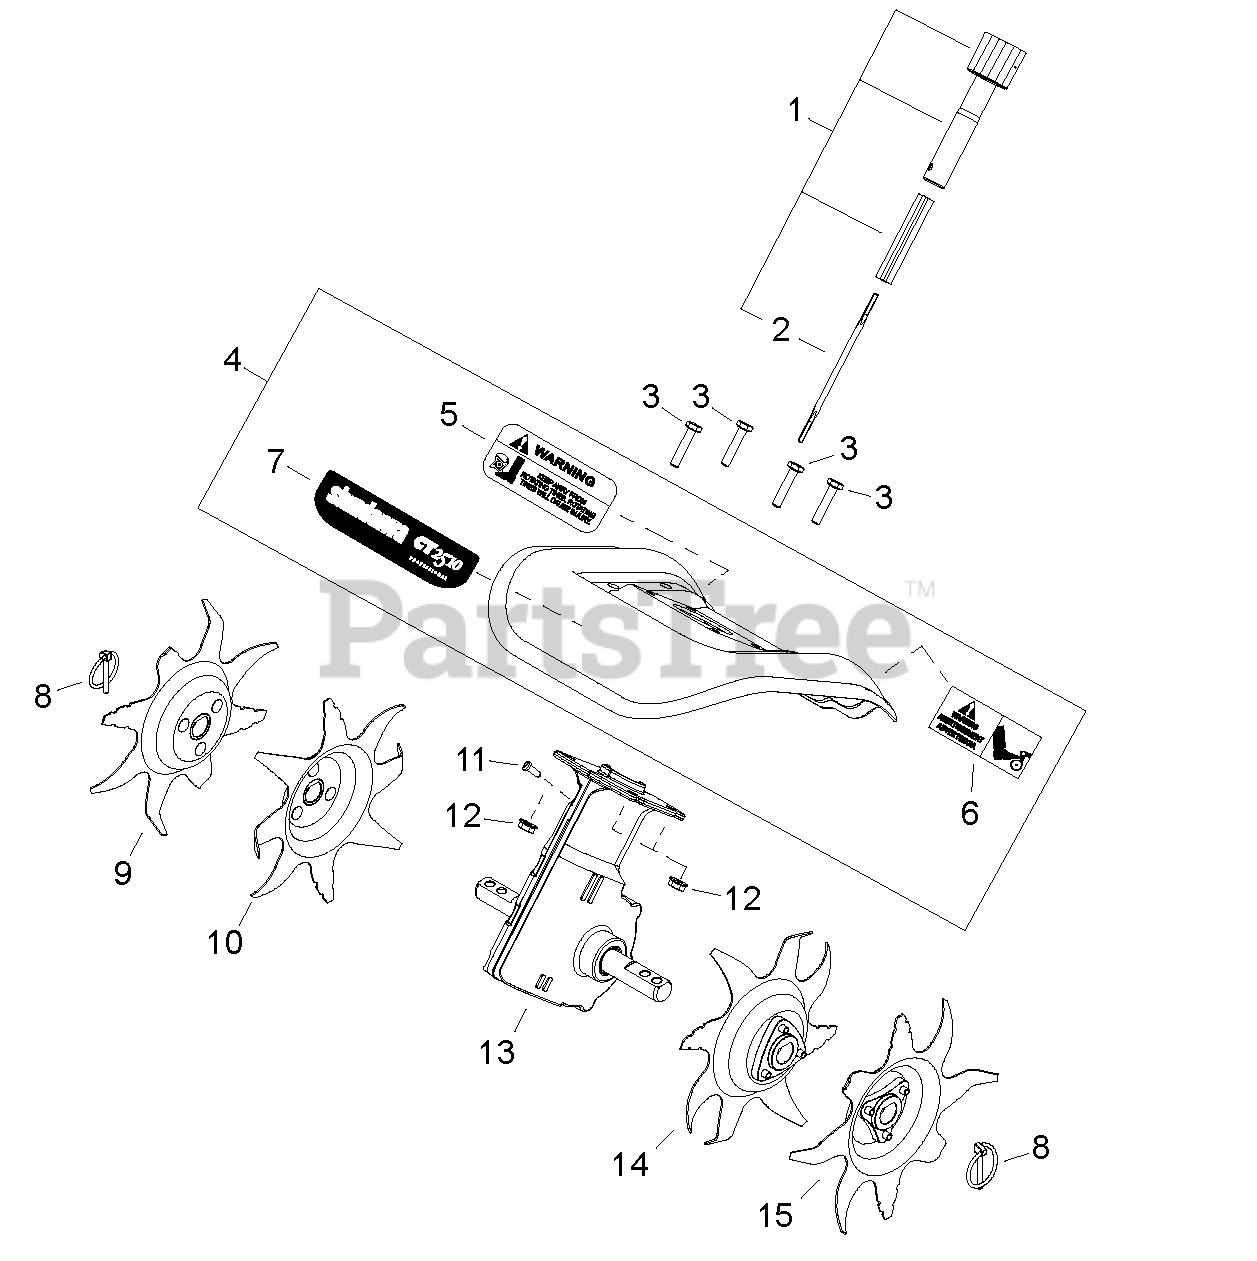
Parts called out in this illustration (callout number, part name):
1	MAIN PIPE ASSY
2	DRIVESHAFT - FLEXIBLE
3	SCREW
4	DEBRIS SHIELD ASSY
5	LABEL - WARNING
6	LABEL - WARNING
7	LABEL - MODEL CT2510
8	PIN, CLICK
9	TINE - OUTER RIGHT
10	TINE - INNER RIGHT
11	SCREW
12	LOCKNUT
13	GEAR CASE ASSY
14	TINE - INNER LEFT
15	TINE - OUTER LEFT
